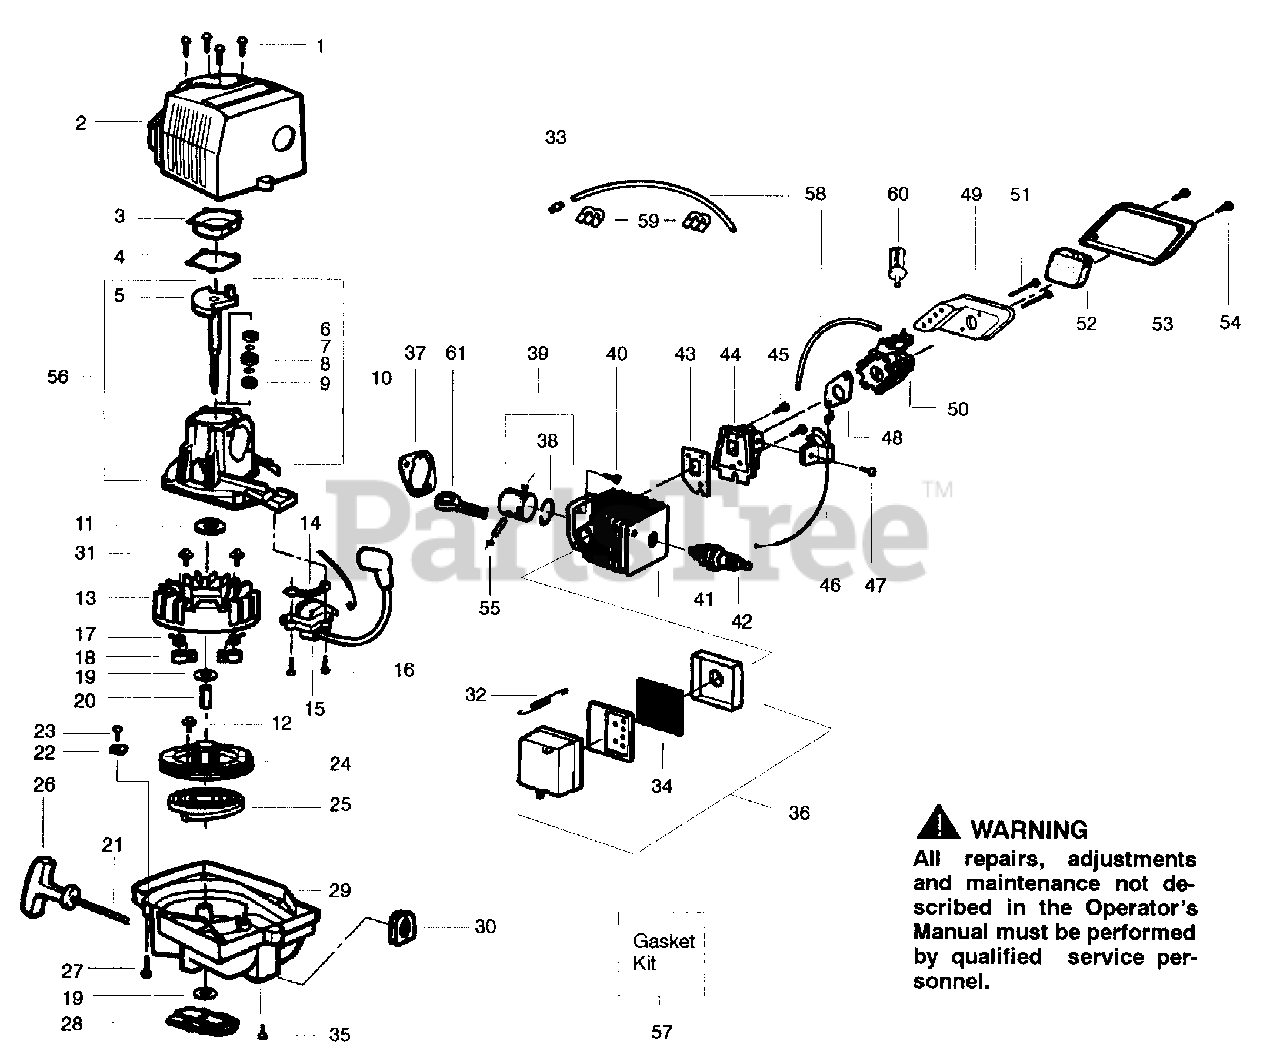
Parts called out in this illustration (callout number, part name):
1	Screw - Shroud
3	Crankcase Cover
4	Gasket-Shrd./C'case
5	Crankshaft Ass'y.
6	Inner Bearing
7	Retainer - C'case
8	Crankcase Seal
9	Outer Bearing
10	Crankcase Ass'y.
11	Retaining Ring
12	Screw - Pulley
13	Flywheel Ass'y.
14	Spacer - Ignit. Mod.
15	Ignition Module
16	Screw - Ignit. Mod.
17	Spring - Starter Dog
18	Starter Dog
19	Washer - Flat
20	Flywheel Spacer
21	Rope Kit
22	Retainer
23	Screw - Retainer
24	Starter Pulley Kit
25	Starter Spring
26	Starter Handle
27	Screw - Fan Housing
28	Clutch Ass'y. Kit
29	Fan Housing
31	Screw - Flywheel
32	Muffler Spring
33	Fuel Line Fitting
34	Muffler Screen
35	Screw - Fan Hsg./Shrd.
36	Muffler Kit
37	Cylinder Gasket
38	Piston Ring
39	Piston Kit
40	Screw - Cylinder
41	Cylinder
42	Spark Plug (RCJ-8Y)
43	Gasket - Cylin./Carb.
44	Carb. Adaptor
45	Screw - Carb. Adap.
46	Throttle Cable Ass'y.
47	Screw - Throtl. Cable
48	Gasket - Carb.
50	Carburetor WT 221 - Type 1
50	Carburetor WT 379 - Type 2
51	Screw - Air Box
52	Air Filter Foam
53	Air Filter Cover
54	Screw - A.F. Cover
55	Piston Pin Retainer
56	C'case & C'shaft Assy.
57	Gasket Kit
58	Fuel Line Kit
59	Retainer Clip
60	Fuel Pick-up Ass'y.
61	Connecting Rod Kit
